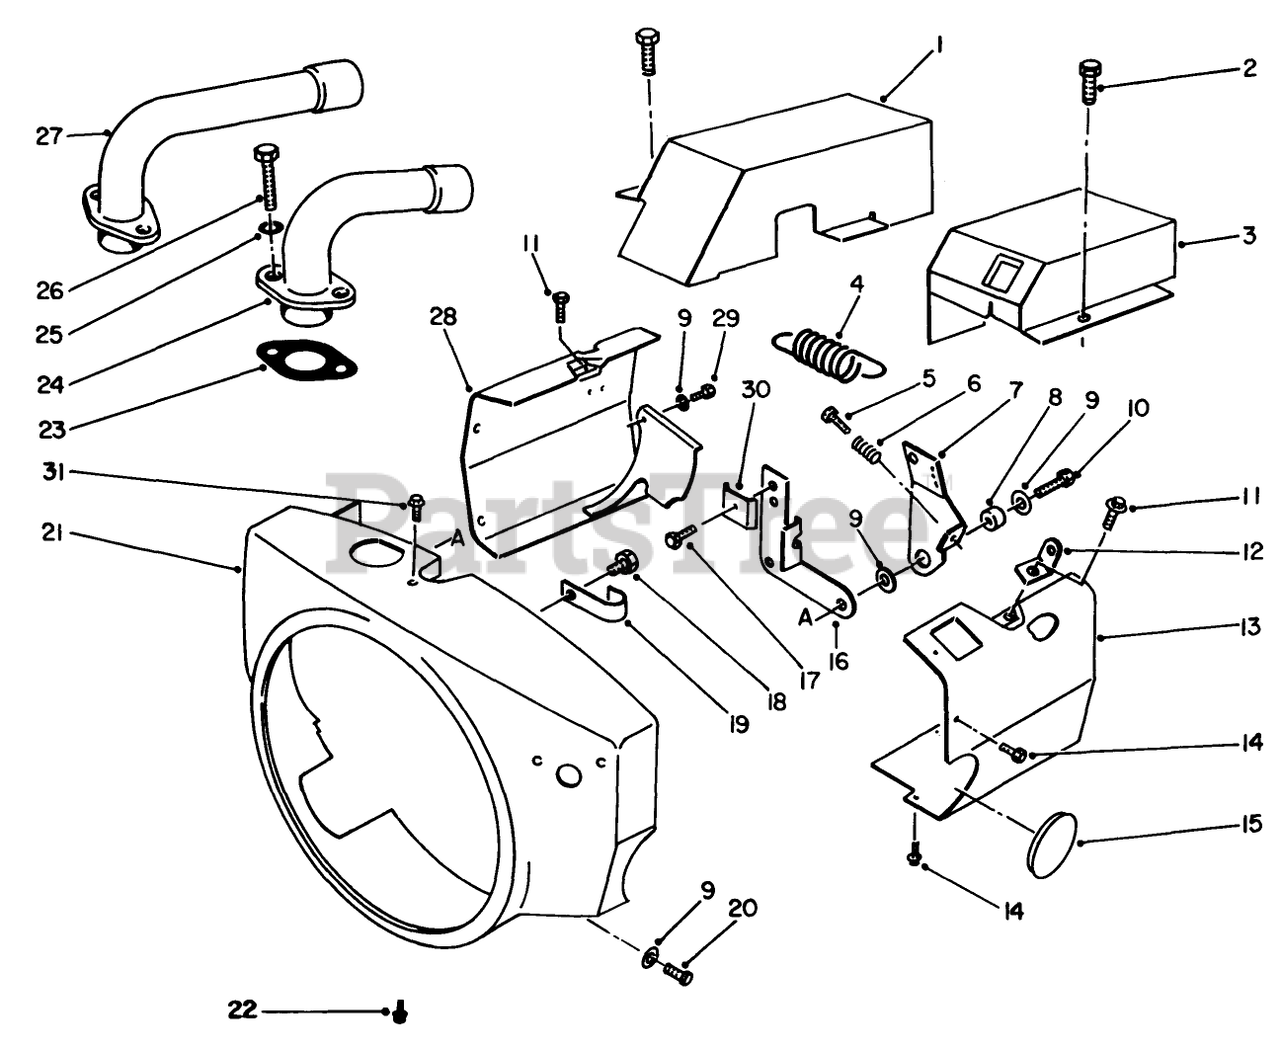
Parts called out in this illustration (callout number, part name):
1	LH EXHAUST TUBE COVERR
2	HX WSHR HD CAPSCREW
3	RH EXHAUST TUBE COVERR
4	SPRING
5	SCREW-TAP
6	SPRING
8	BUSHING
9	WASHER-FLAT
10	SCREW-HWH
11	SCREW-HHF
12	Bracket-Lift
13	CYL AIR HOUSING ASSY
14	SCREW-HWH
15	AIR SEAL GROMMET
16	BRACKET-GOVERNOR
17	SCREW-TAPPING
18	SCREW-HHF
19	CLIP-WIRE
20	SCREW-HH
21	Housing-Blower
22	HEX HD CAPSCREW
23	Gasket
24	EXHAUST TUBE
25	WASHER-FLAT
26	SCREW-HH
27	EXHAUST TUBE
28	Housing-L.H.
29	SCREW-HH
31	SCREW-HWHTF
